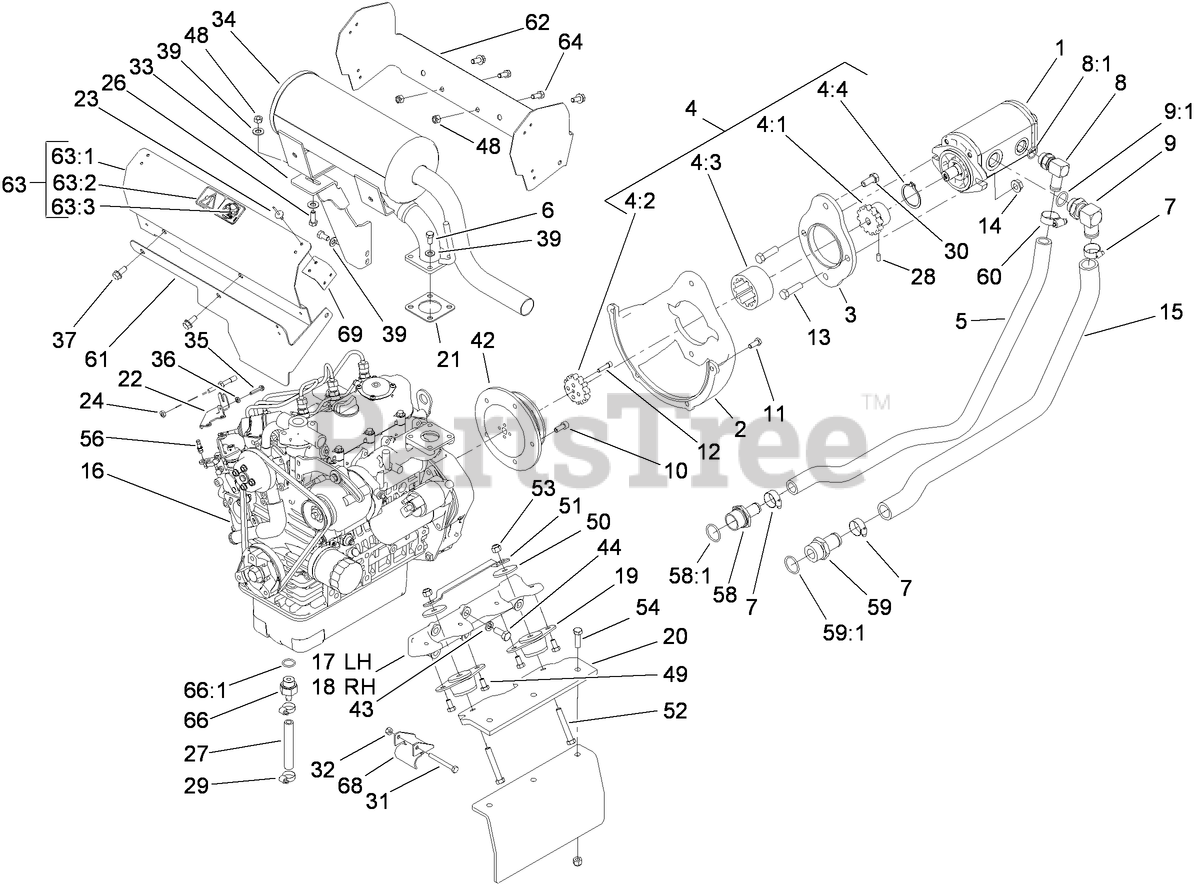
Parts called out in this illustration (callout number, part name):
1	PUMP-HYD
2	PUMP-MOUNT
3	PLATE-MOUNT, PUMP
4	COUPLING ASM
4:1	HUB-COUPLING
4:2	SLEEVE-HUB
4:3	SLEEVE-COUPLING
4:4	RING-SNAP, COUPLING
5	HOSE-FORMED, SUCTION
6	BOLT
7	CLAMP-HOSE
8	FITTING
8:1	O-RING
9	FITTING-HYD, 90 DEG
9:1	O-RING
10	SCREW-CAP, HSH
11	SCREW-HH
12	SCREW-HSH
13	SCREW-HH
14	NUT-HF
15	HOSE-FORMED, SUCTION
16	ENGINE-KUBOTA, D902
17	MOUNT-ENGINE, LH
18	MOUNT-ENGINE, RH
19	MOUNT-ENGINE
20	PLATE-MOUNT, ENGINE
21	GASKET-MUFFLER
22	BRACKET-SUPPORT, THROTTLE
23	RIVET
24	NUT-JAM
26	SCREW-HH
27	HOSE-DRAIN, ENGINE OIL
28	SCREW-SET, HSH
29	CLAMP-HOSE
30	SCREW-HH
31	SCREW-HH
32	NUT-LOCK, CONE
33	SUPPORT-MUFFLER
34	MUFFLER ASM
35	SCREW-HWHTF
36	NUT-HEX
37	SCREW-HHF
39	WASHER-PLAIN
42	PULLEY-MACHINED
43	WASHER-LOCK, SPRING
44	SCREW-HH
48	NUT-LOCK, CONE
49	SCREW-HH
50	WASHER-REBOUND
51	STRAP-REBOUND
52	SCREW-HH
53	NUT-LOCK, NI
54	SCREW-HH
56	SWIVEL-STOP, CABLE
58	FITTING-HOSE, BARBED
58:1	O-RING
59	FITTING-STR
59:1	O-RING
60	CLAMP-HOSE
61	PLATE-BAFFLE, LOWER
62	PLATE-BAFFLE
63	HEAT SHIELD BAFFLE ASM
63:1	PLATE-BAFFLE, MUFFLER
63:2	PLATE-HOT SURFACE
63:3	RIVET-POP
64	SCREW-HH
66	FITTING-HOSE
66:1	GASKET
68	GUIDE-CABLE
69	BRACKET-SHIELD
